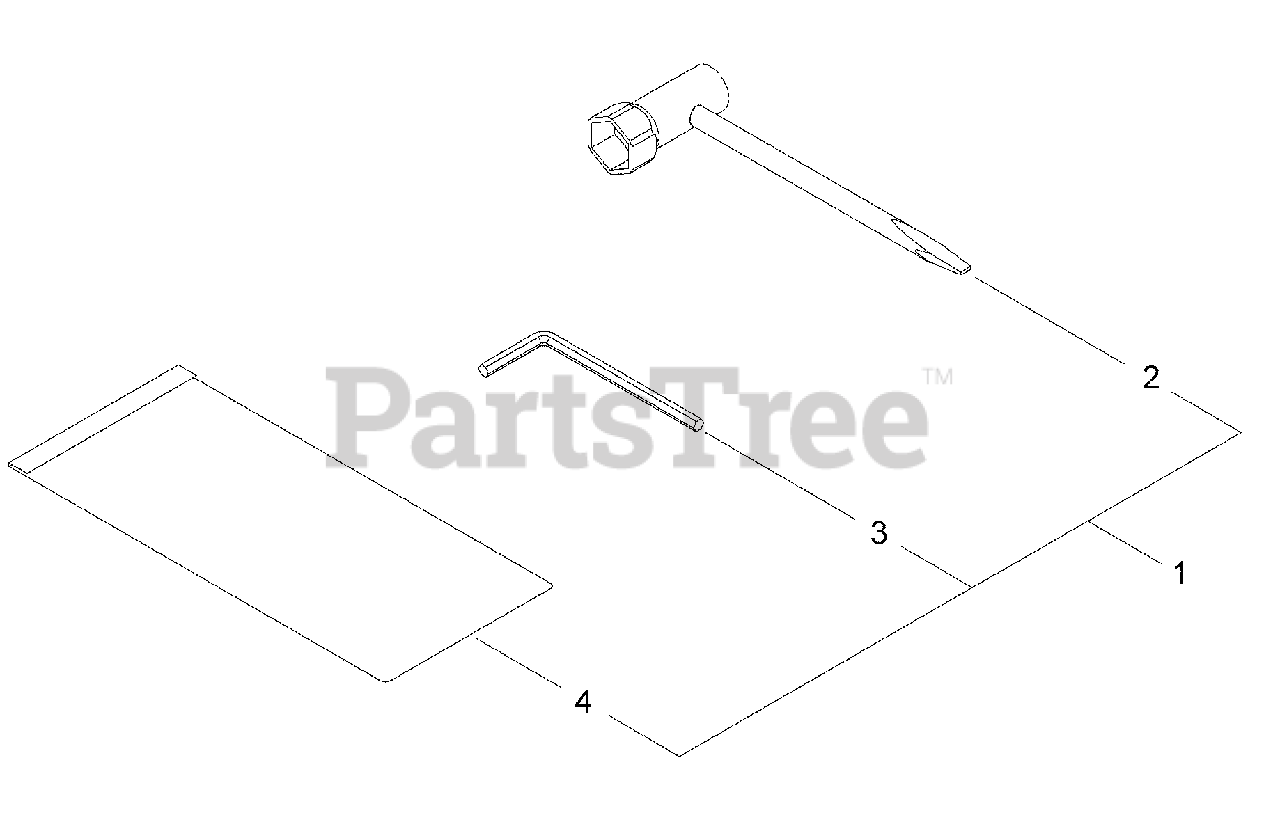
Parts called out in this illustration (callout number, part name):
1	TOOL KIT
2	T-WRENCH - 13X16mm
3	HEX KEY - 4mm
4	BAG, TOOL
